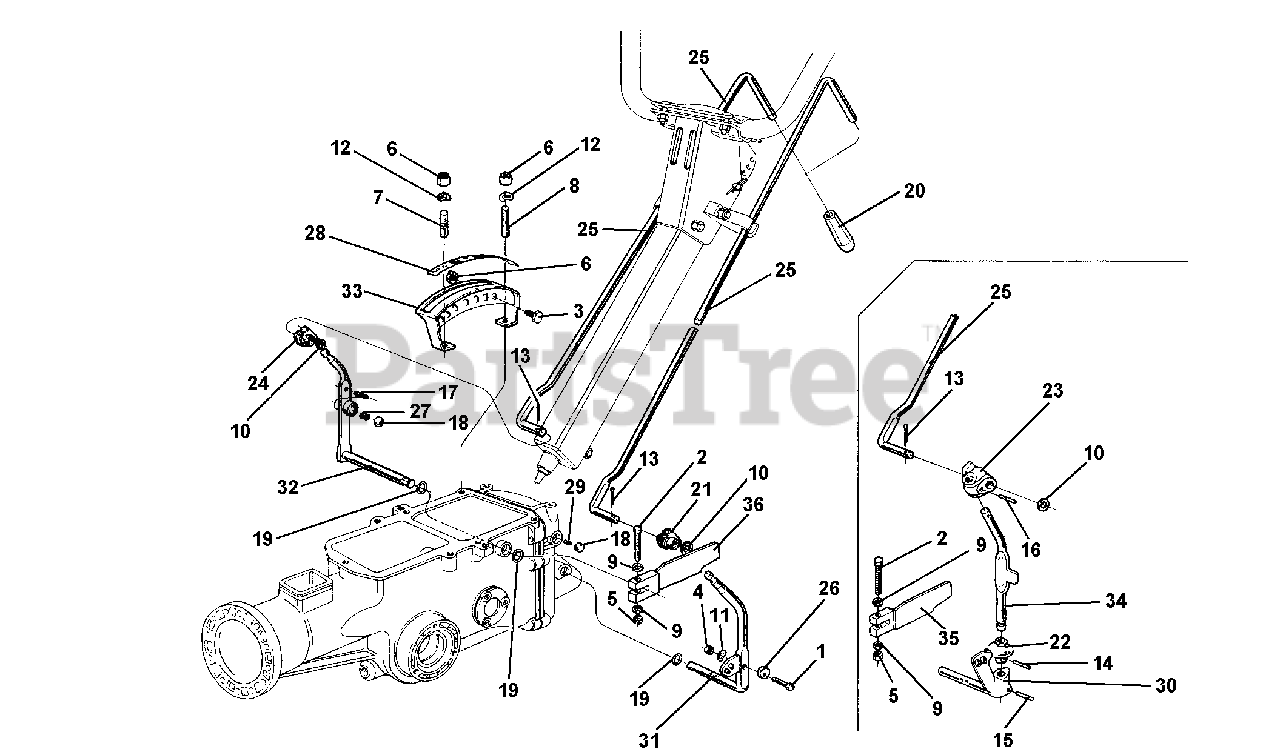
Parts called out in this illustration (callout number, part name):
1	SCREW M6 X 25
2	SCREW M6 X 40
3	SCREW M8 X 14
5	NUT, SELF LOCKING M6
6	NUT, SELF LOCKING M8
7	STUD M8 X 38 X 14 X 20
8	STUD M8 X 46 X 16 X 16
9	WASHER, FLAT 6.4
10	WASHER P10.5 X 18
11	WASHER, LOCK 6.4
12	WASHER, LOCK 8.4
14	LOCKING PIN 4 X 20 SPIRAL
16	LOCKING PIN 4 X 24 SPIRAL
17	LOCKING PIN SPIRAL
18	BALL 15/32 RIV RB-11.906
19	O-RING 115 11.91 X 2.62
21	JOINT, D 10
22	P.T.O. STOP RING
23	P.T.O. ARTICULATION
25	ROD, CONTROL, POWER TILLER
28	PLATE 5 SPEEDS WALKING TRAC
29	P.T.O. SPRING
31	P.T.O. LEVER
32	GEARBOX LEVER
34	P.T.O. CONTROL LEVER
35	P.T.O. LOCKOUT
36	P.T.O. LOCKOUT
